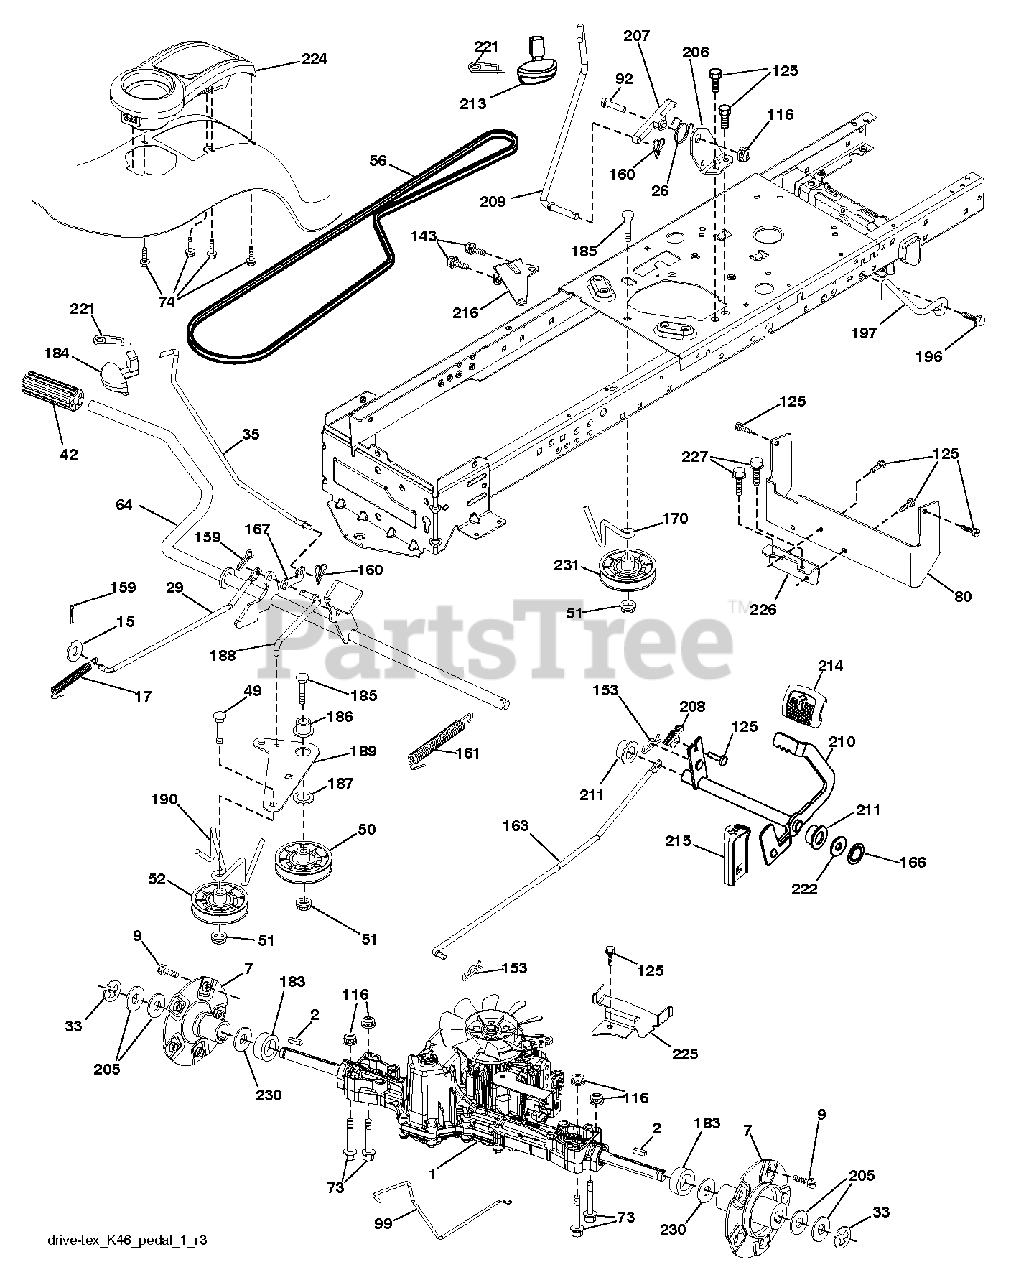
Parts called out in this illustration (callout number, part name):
2	KEY.SQUARE.187X2.500
7	HUB.ASM.WHEEL.REAR.22"
17	SPRING.BRAKE.K46.GREEN
26	SPRING.RETURN.CRUISE
29	ROD.BRAKE.K46
33	E-RING LT
35	ROD.BRAKE.PARKING.GT.H
42	PEDAL COVER T
49	BOLT
50	IDLER.FLAT.910.OFFSET
51	NUT LOCK FLG 3/8-16 UNC
52	IDLER.V-GROOVE.910.OFFSET
64	SHAFT.ASM.PEDAL.BRK.CNTR
74	SCREW.HI-LO.CONSOLE
80	STRAP TORQUE
92	BOLT
99	ROD.SPRING.BYPASS.K46.LT.Z
116	NUT LOCK HEX FLANGE 5/16-18
125	SCREW
153	RETAINER M
159	COTTER PIN
160	RETAINER CLIP
161	SPRING, RETURN LT
166	NUT.PUSH.625
167	LATCH.BRAKE.SPRING
170	KEEPER.CENTER SPAN.1.688
183	SPACER.SPLIT.800X.350
184	HANDLE.PARKG.BRK.HUSQ/
186	SPACER.RETAINER
187	WASHER 12/32X2X10GA
188	LINK.CLUTCH.GROUND.DRIVE
189	BELLCRANK.GROUND.DRIVE.TEX.
190	KEEPER.BELLCRANK.DRIVE
196	SCREW 3/8-16X1
197	BRKT.ANIT-ROTATION.CLU
206	BRKT.MOUNT.LATCH.CRUIS
207	LATCH.CONTROL.CRUISE
208	GEAR.SECTOR.CONTROL.CR
209	ROD.CONTROL.CRUISE.GT.
210	ROCKER.ASM.PEDAL.CONTR
211	BEARING.NYLON
213	KNOB.CONTROL.CRUSIE.HU
214	PAD PEDAL FORWARD
215	PEDAL.REVERSE.TEX.GT.4
216	BRACKET.PULLEY.IDLER.W/TEX
221	RETAINER.SPRING.CLIP.H
222	WASHER 21/32 X 1-1/4 X 10 GA.
224	CONSOLE.TOOLBOX.PCH.ERGO.BLACK
225	KEEPER.BELT.TRANSAXLE.K46
226	BRACKET.MOUNT.TORQUE.K46.TLT
227	SCREW
230	WASHER.HARDENED
231	IDLER.V-GROOVE.1.688.OFFSET
